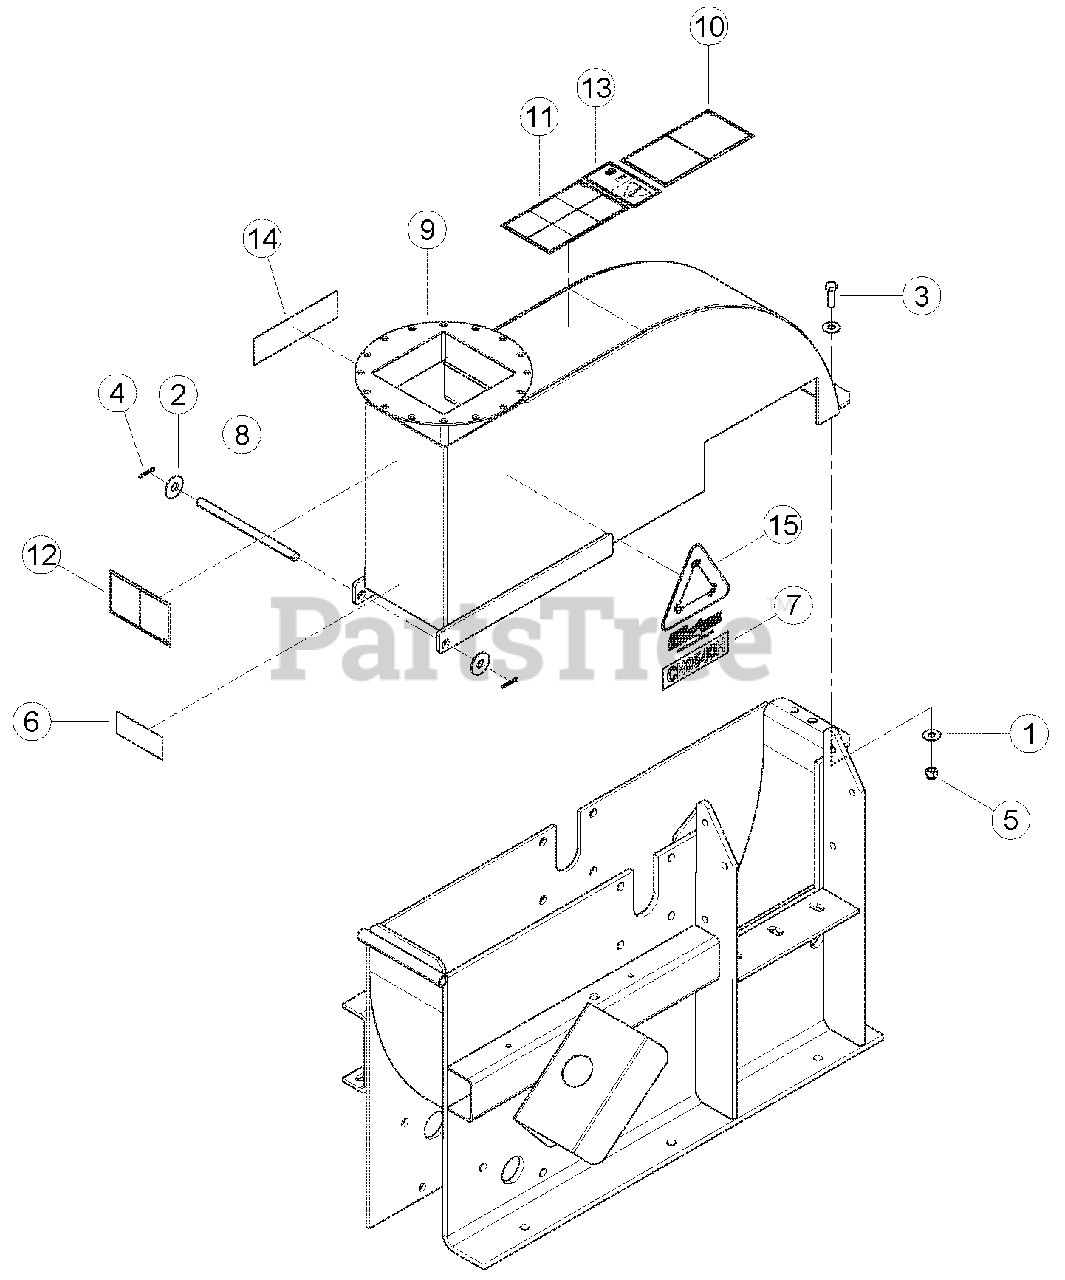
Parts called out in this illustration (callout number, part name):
1	WASHER, 3/8 FLAT ZP
2	WASHER, 1/2 FLAT ZP
3	BOLT, 3/8 X 1-1/4 HEX HD GR5 ZP
4	PIN, 1/8 X 1.00 ZP COTTER
5	NUT, 3/8 NE NYLOCK ZP
6	DECAL, ATLANTIC BRIDGE LTD INFO (CE COMPLIANT MODELS)
7	DECAL, MODEL CH9540H
8	SHAFT, CHIPPER TOP PIVOT
9	ASSEMBLY, CHIPPER TOP HOUSING, SERVICE PART
10	DECAL, KNIFE ACCESS ISO
11	DECAL, OPERATING INSTRUCTIONS ISO
12	DECAL, DISCHARGE ISO
13	DECAL, MAINTENANCE ISO
14	DECAL, ECHO BEARCAT 6.82 X 1.90
15	DECAL, CHIP IT
